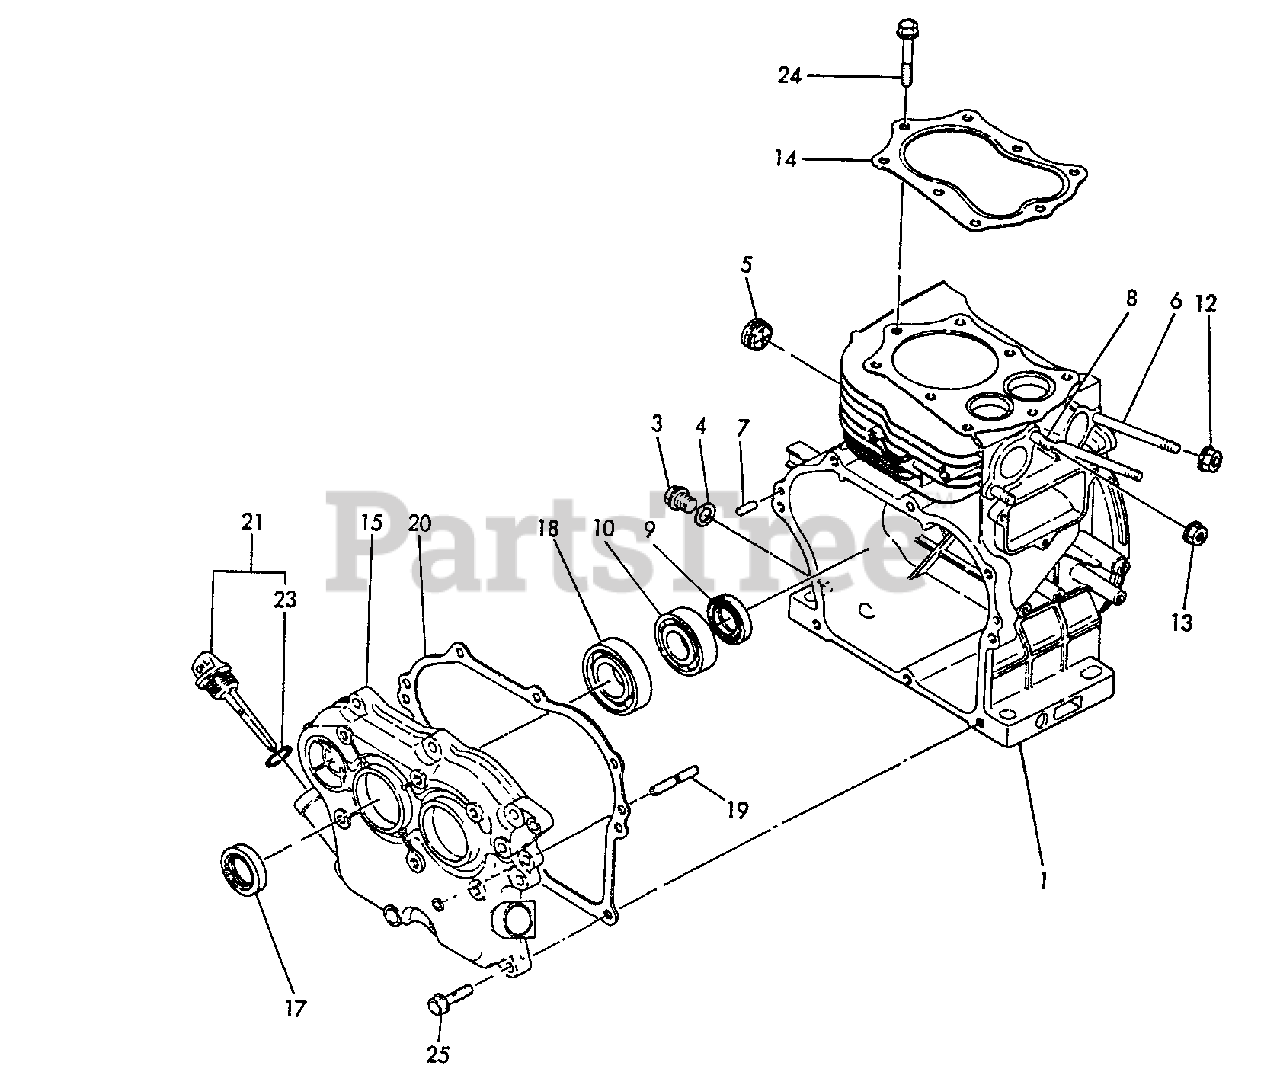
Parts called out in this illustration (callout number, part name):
1	CYLINDER BLOCK SET
3	PLUG, DRAIN
4	GASKET
5	PLUG
6	BOLT - 6×90
7	PARALLEL PIN 6×16
8	STUD - 8×18 -- PLATED
9	SEAL, OIL
10	BEARING, BALL
12	U-NUT M6
13	U-NUT M8
14	GASKET, CYLINDER
15	SIDE COVER ASSY
17	SEAL, OIL
18	BEARING, BALL 6206C4
19	SHAFT, GOVERNOR
20	GASKET, SIDE COVER
21	CAP ASSY
23	O-RING 1A P-18.0
24	BOLT - 8×50
25	BOLT - 8×30 -- PLATED
